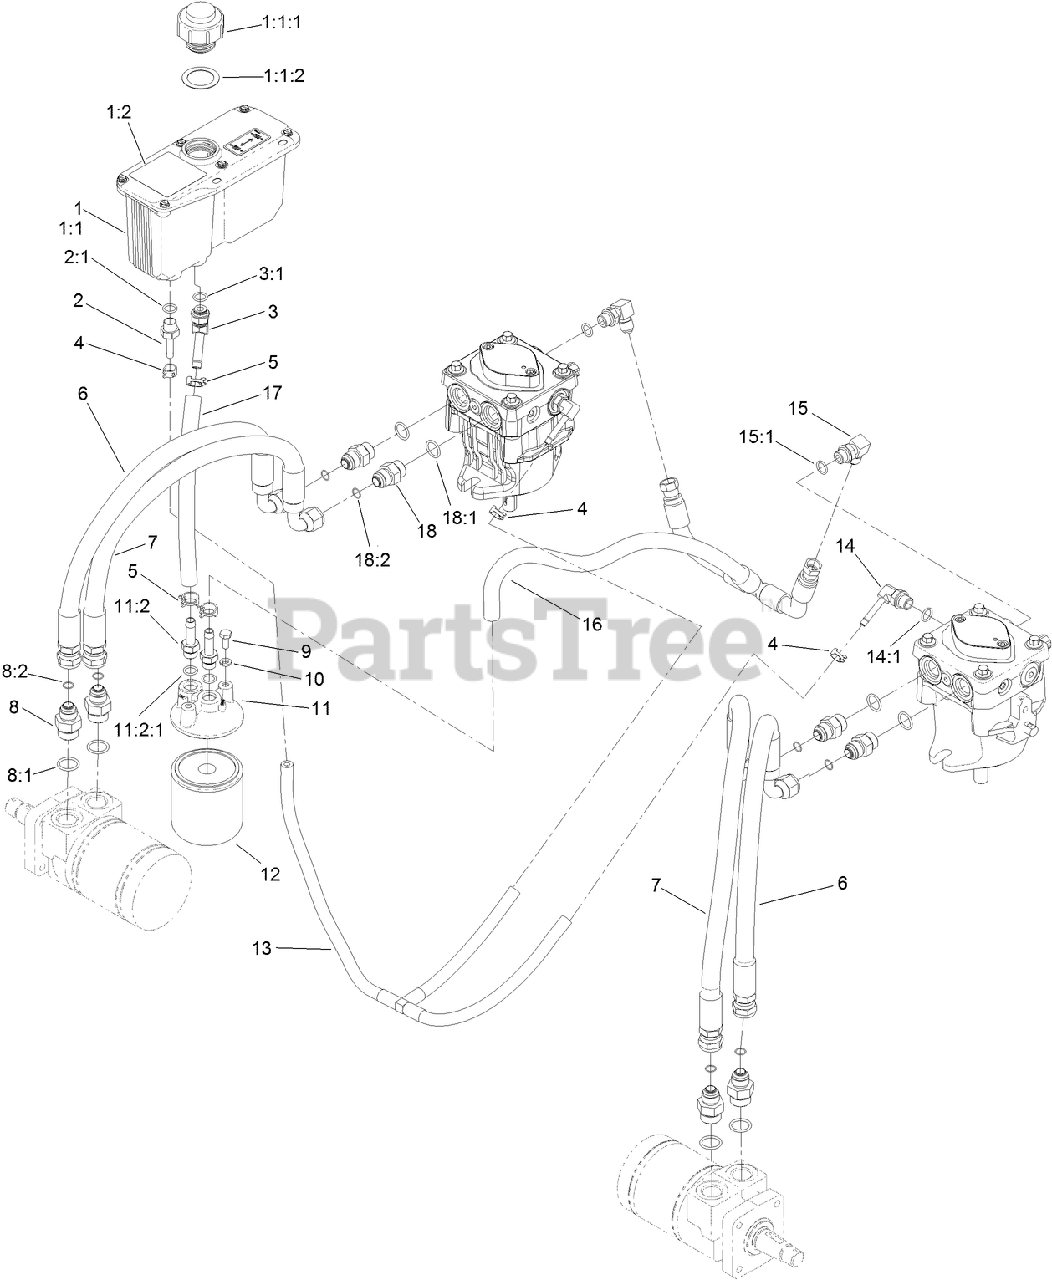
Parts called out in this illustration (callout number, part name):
1	HYD RESERVOIR ASM
1:1	Reservoir-HYD
1:1:1	CAP-RESERVOIR, HYD
1:1:2	GASKET-CAP
1:2	DECAL-WARNING
2	ADAPTER-STRAIGHT
2:1	O-RING
3	FITTING-BARBED, 45 DEG
3:1	O-RING
4	CLAMP-HOSE
5	CLAMP-HOSE
6	HYD HOSE ASM
7	HYD HOSE ASM
8	FITTING-STRAIGHT
8:1	O-RING
8:2	O-RING
9	SCREW-HH
10	WASHER-LOCK
11	FILTER HEAD ASM
11:2	ADAPTER-STRAIGHT
11:2:1	O-RING
12	FILTER-OIL, HYD
13	CASE DRAIN HOSE ASM
14	ELBOW-90 DEG
14:1	O-RING
15	FITTING-ELBOW, 90 DEG
15:1	O-RING
16	CHARGE HOSE ASM
17	HOSE-CHARGE
18	FITTING-STRAIGHT
18:1	O-RING
18:2	O-RING
